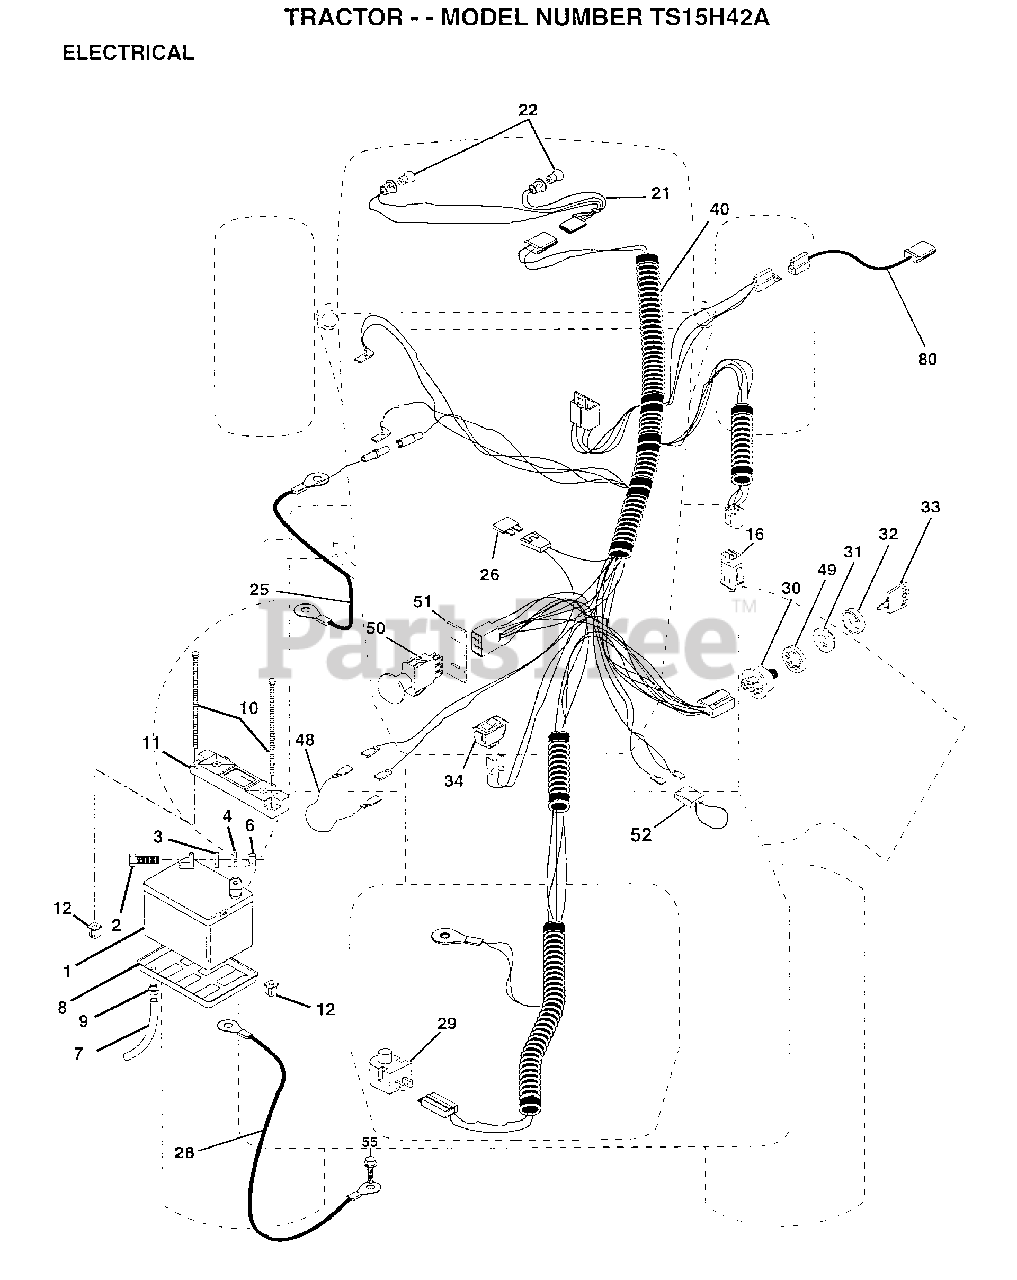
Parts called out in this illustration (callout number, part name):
2	BOLT LT
3	WASHER
4	LOCKWASHER
7	"DRAIN TU T, BATT"
8	"TRAY T, BATTERY"
9	HOSE CLAMP T
16	SWITCH INTERLOCK
21	HARNESS.ASM.HDLIG
22	HEADLAMP BULB
25	"CABLE.6GA.RED.40"""
26	FUSE HYT
28	CABLE.GRND.6GA.21
29	SWITCH SEAT
32	COVER KEY SWITCH
33	KEY
34	SWITCH LT
40	HARNESS IGNITION
44	NUT
48	ADAPTER AMMETER
49	WASHER PINNED
51	RING RETAIN PTO
52	PROTECTION LOOP
55	SCREW LT
80	HARNESS.CLUT.EVX.
